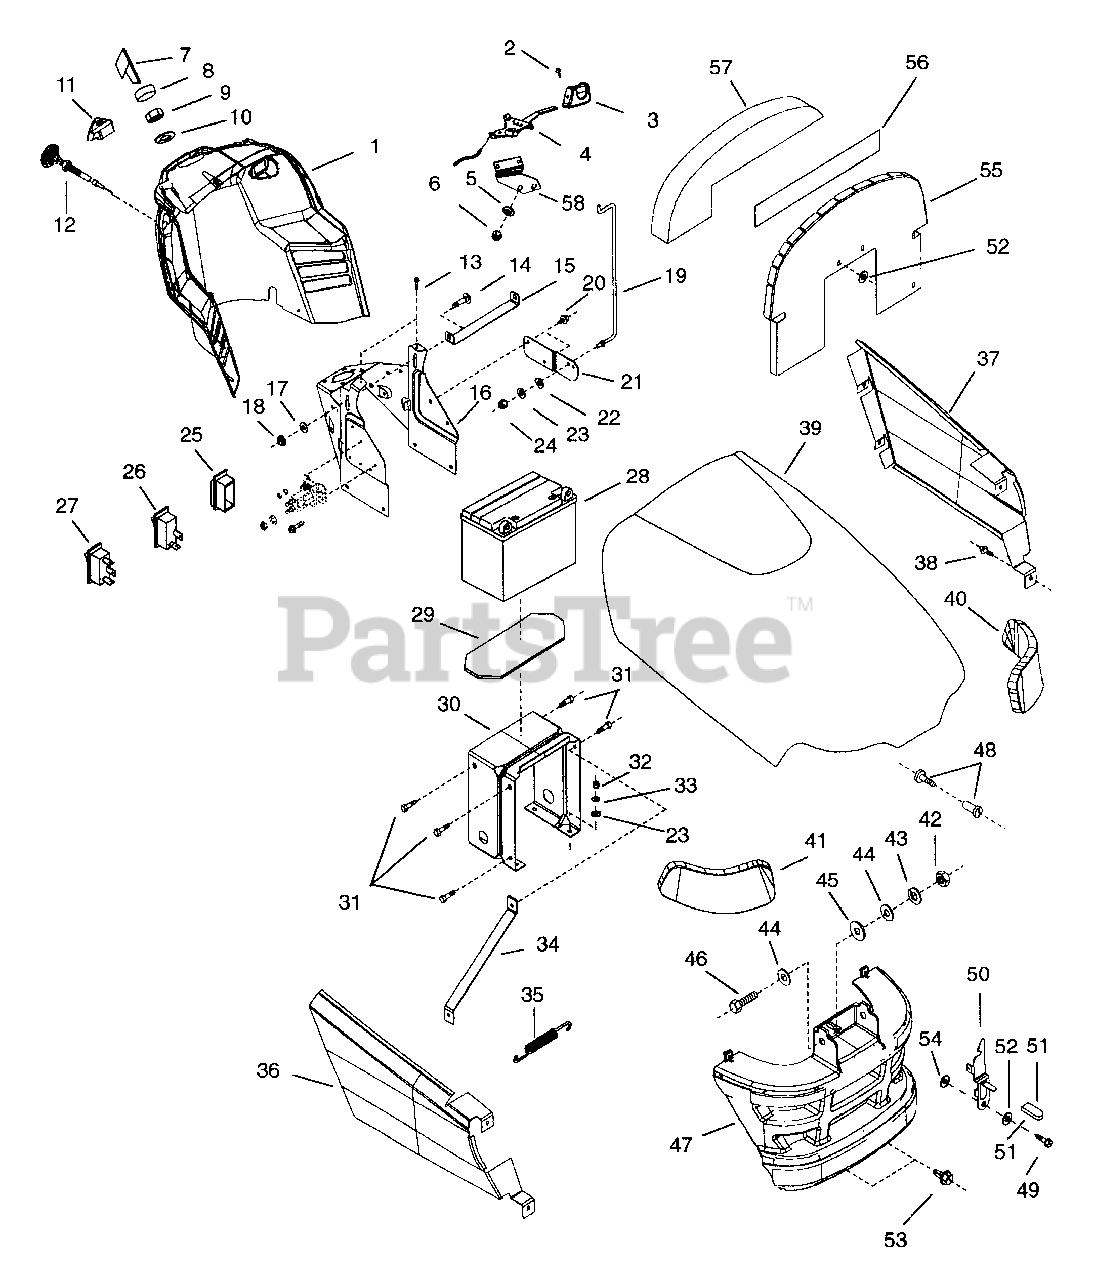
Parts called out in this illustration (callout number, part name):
1	DASH
2	SCR-SET 10-24X.38 UNC-3A
3	KNOB - THROTTLE
4	THROTTLE CONTROL- TEC/B&S
4	THROTTLE CONTROL- 15 KOHLER
5	WSHR-LK 10X.047 MED PL
6	NUT-HEX 10-24 PL
7	KEY -W/CAP
8	CAP - IGNITION SWITCH
9	NUT- PANEL .562-24 GRECO
10	WSHR-LK-INT .563X.040 PL
11	PTO KNOB/ SWITCH ASSY
12	CHOKE CABLE
13	SCR-TAP 10-24X.375 CRPH 1A
14	BLT-RDHDSQNK .312-18X.62SHTPL
15	HOLDDOWN - BATTERY
16	SUPPORT - DASH - TOP
17	WSHR-FL-STL .323X.625X.062 PL
18	NUT-LK .312-18 GR A PL
19	ROD - HOOD PROP
20	SCR-TAP .250-20X.37 HWH PL TR
21	MOUNT - PROP ROD
22	WAVE WASHER .390X.655X.110
23	WSHR-FL-STL.312X.734X.065PL
24	NUT-LK-CTR .250-20 PL
25	COVER - SWITCH
26	SWITCH - LIGHT
27	SWITCH - CRUISE
28	BATTERY W/TUBE
29	RUBBER PAD
30	SUPPORT DASH BASE
31	SCR-TAP .312-18X.50 HWH PL TR
32	NUT-HEX .312-18
33	WSHR-LK .312X.097 PL HVY
35	SG-TENS .035X.45X2.75 WLD 3.5
36	SIDE PANEL- RH
37	SIDE PANEL- LH
38	SCR-TAP 12-16X.500 HI-LOTPHBL
40	HEADLIGHT- LH
41	HEADLIGHT- RH
42	NUT-HEX .375-16
43	WSHR-LK .375X.094 MED PL
44	WSHR-FL-STL.406X.812X.065PL
45	WSHR-FL-NYL .390X1.000X.062
46	BLT-HEX .38-16X1.00 PL GR5
47	GRILLE
48	POST & SCREW-RAPIDASSY 1.000
49	SCR-TAP 12-24X.50 HWH TR BLACK
50	HOOD LATCH
51	GRIP .062 X .375 X 1.000 RE
52	WSHR-FL-STL .281X1.250X.048 BL
53	SCR-TAP .312-18X.50 HWH TR BL
54	WSHR-FL-STL.344X.688X.065PL
55	BAFFLE- STEEL
56	RUBBER SEAL 15IN
57	BAFFLE- HOOD
58	BRACE-THROTTLE CONTROL
